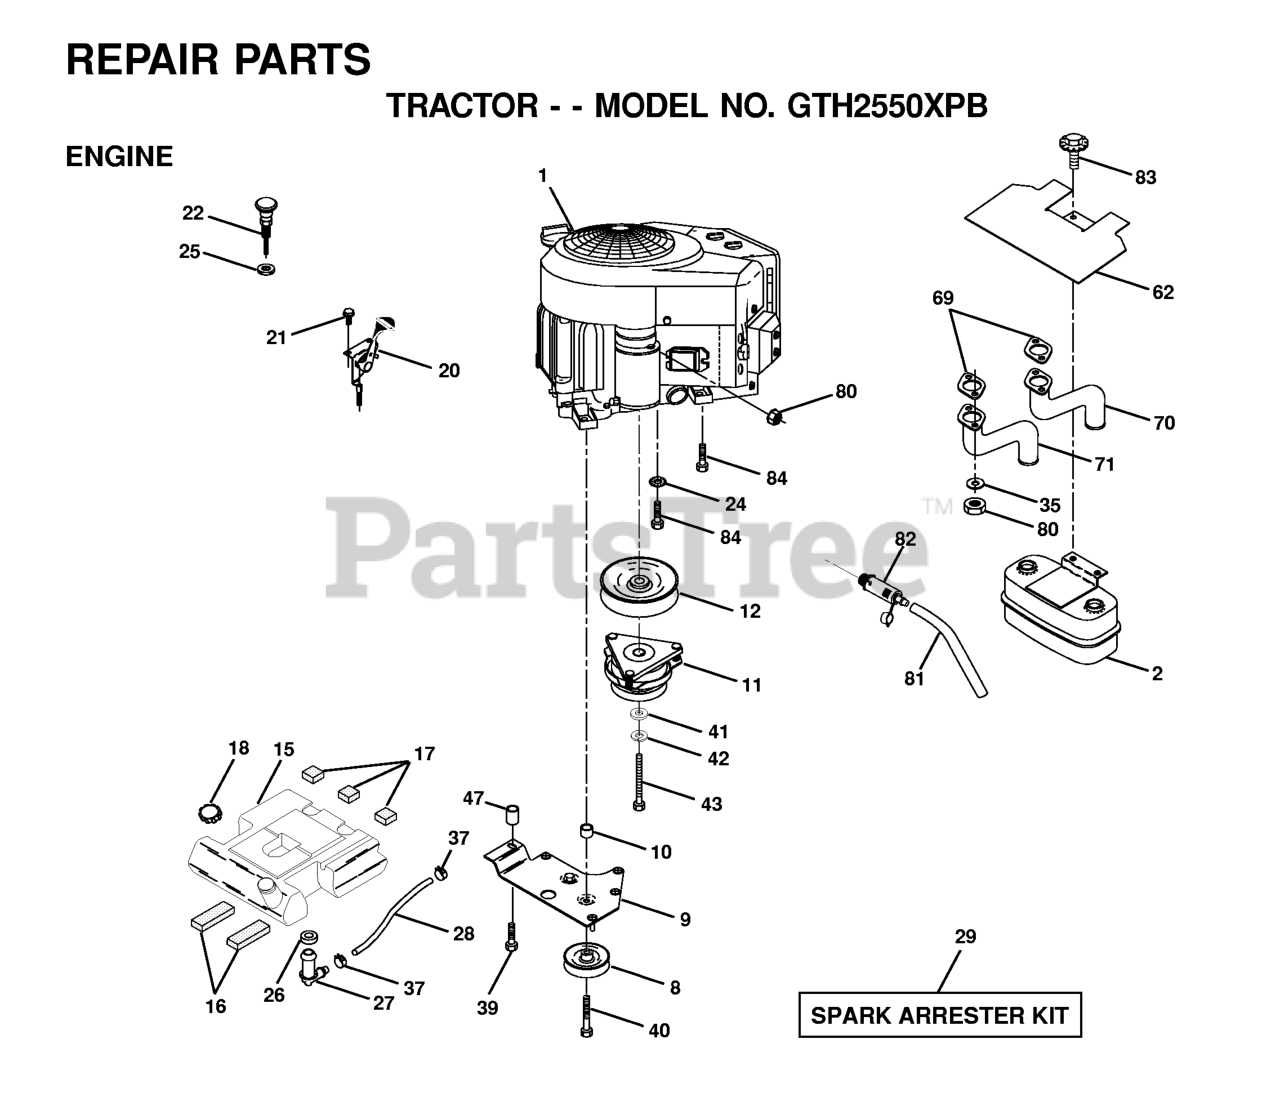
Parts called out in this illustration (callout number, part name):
2	MUFFLER.TWIN.CYL.LOW.TONE
8	RP.IDLER GROOVED
9	KEEPER ASM BELT ENGINE
12	PULLEY ENG VGT ELECT CLUTCH
15	FUEL TANK 3.5G
16	PAD IDLER TI
17	PAD-SPACER LT
18	CAP, FUEL GUAGE
20	CONTROL.THROTTLE.COBRA.42"BLK.
21	SCREW
22	CHOKE CONTROL
24	LOCKWASHER
25	Nut Keps 3/8 - 24 UNF
26	BUSHING OUTLET T
27	STEM FUEL TANK
28	FUEL LINE
29	KIT.SPARK ARRESTOR 794945 B&S
37	HOSE CLAMP
39	SCREW TT 3/8-16X2-1/4 UNC
40	Screw TT 3/8-16 x 4 unc
42	LOCKWASHER
43	BOLT HEX 7/16-20X4-1/4"
62	HEAT SHIELD
70	TUBE EXHAUST LH
71	TUBE.EXHAUST.KAWASAKI.RH
80	FLANGE NUT
81	TUBE, DRAIN OIL ASM.
83	BOLT.5/16-18UNCX3/4 W/SEMS.BLK
84	SCREW 3/8-16 X 1-1/2
